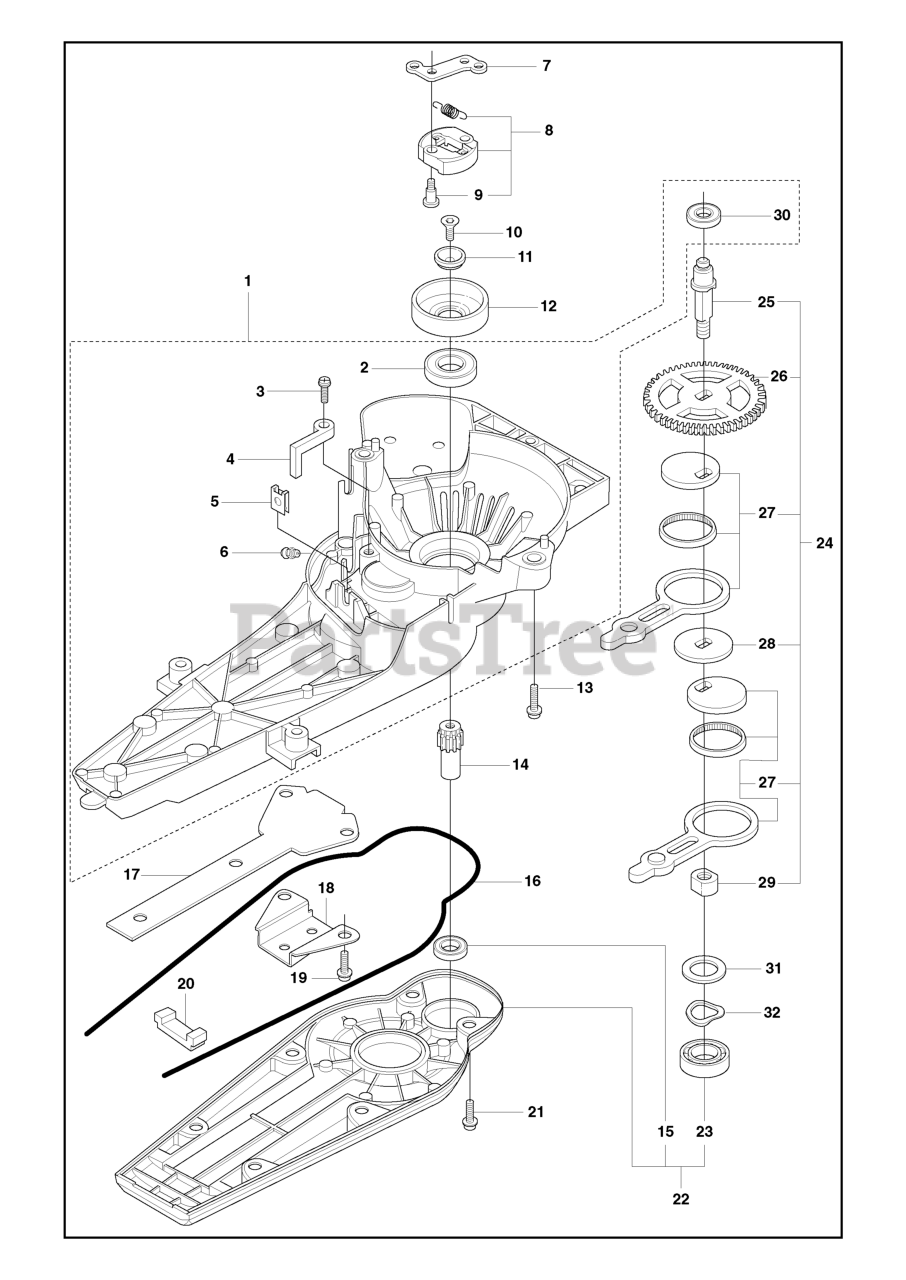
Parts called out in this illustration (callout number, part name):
1	REAR HANDLE COMPLETE
2	HANDLE PART
3	THROTTLE LOCK
4	THROTTLE TRIGGER
5	STOP BUTTON
12	HEAT PROTECTOR EXHAUST PIPE
13	VIBRATION ABSORBER
19	VIBRATION ABSORBER
